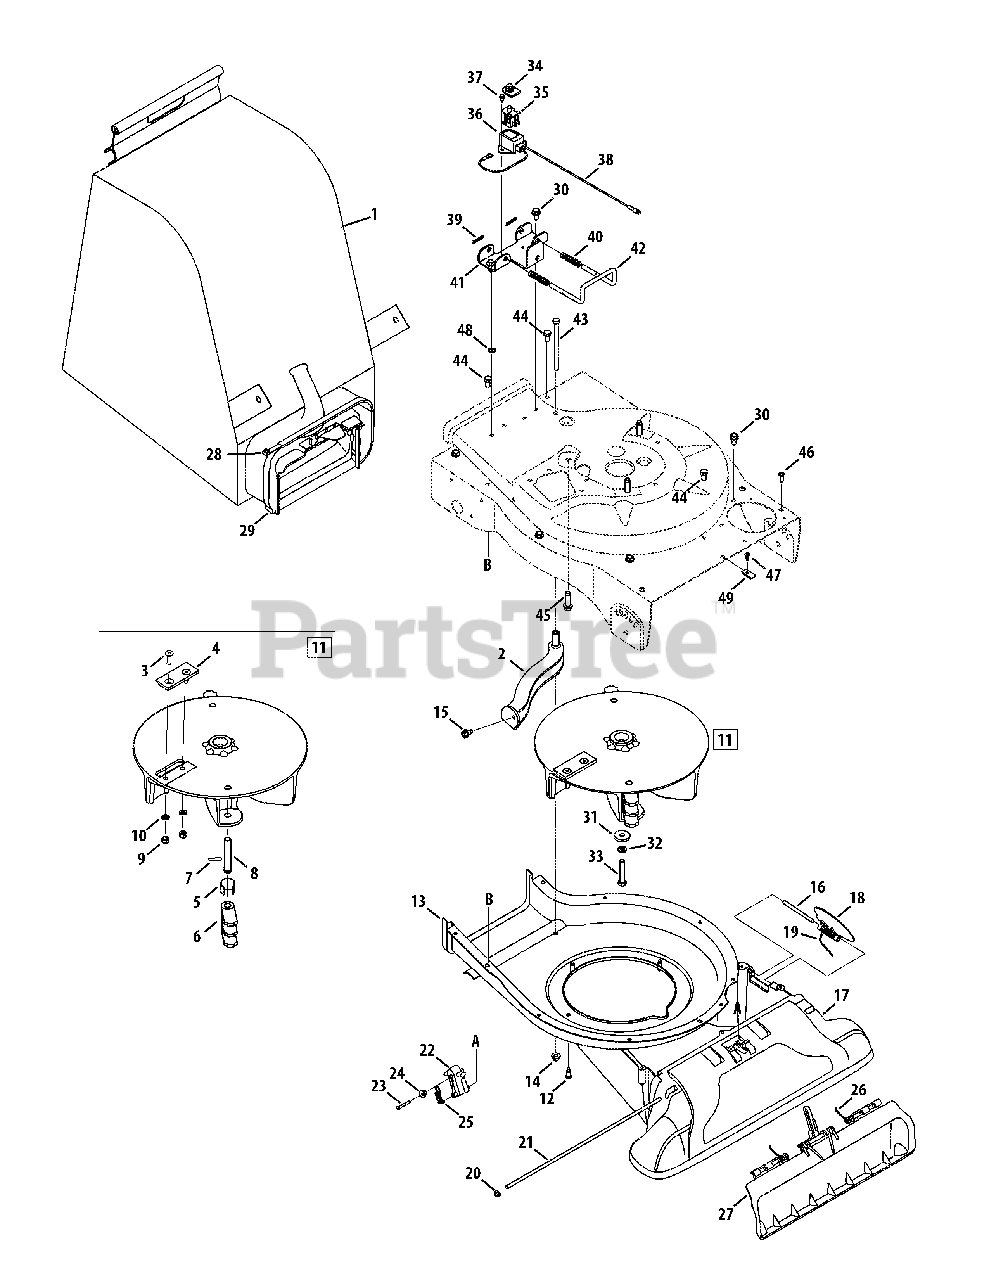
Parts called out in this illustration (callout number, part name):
1	Bag Assembly (incl. Ref 28)
2	Screen Assembly
3	Hex Screw 5/16-24 x 1.0
4	Chipper Blade
7	Spiral Pin
8	Clevis Pin
9	Lock Nut, 5/16-24
10	Lock Washer, 5/16
11	Impeller Assembly
12	Shoulder Screw, #12-24 x.30 x.46
13	Lower Flail Housing
14	Flange Lock Nut 5/16-18
15	Screw, 5/16-18 x.500
18	Base Adapter Door
19	Torsion Spring
20	Cap Speed Nut 1/4
21	Pivot Rod
22	Nozzle Door Lever
23	Hex Screw, #8-18 x 1.25
24	Shoulder Spacer
25	Extension Spring
26	Nozzle Door Torsion Spring
27	Nozzle Door
28	Tie Strap, 42"
29	Chute Assembly
30	Hex Index Screw, 5/16-12 x.750
31	Flat Washer.375 ID x 1.25 OD
32	Lock Washer 3/8
33	Hex Cap Screw 3/8-24 x 2.0
34	Switch Cover
35	Safety Switch
36	Safety Switch Cover
37	Hex Washer Screw #10-16 x.50
38	Wire Harness
39	Cotter Pin
40	Compression Spring
41	Mounting Bracket
43	Hex Cap Screw 5/16-18 x 4.5
44	Hex Cap Screw 5/16-18 x.625
45	Hex Washer Screw 3/8-16 x 1.00
46	Screw, #12-16 x.750
47	Screw #10 - 16 x.500
48	External L-Washer 5/16
49	Speed Nut
